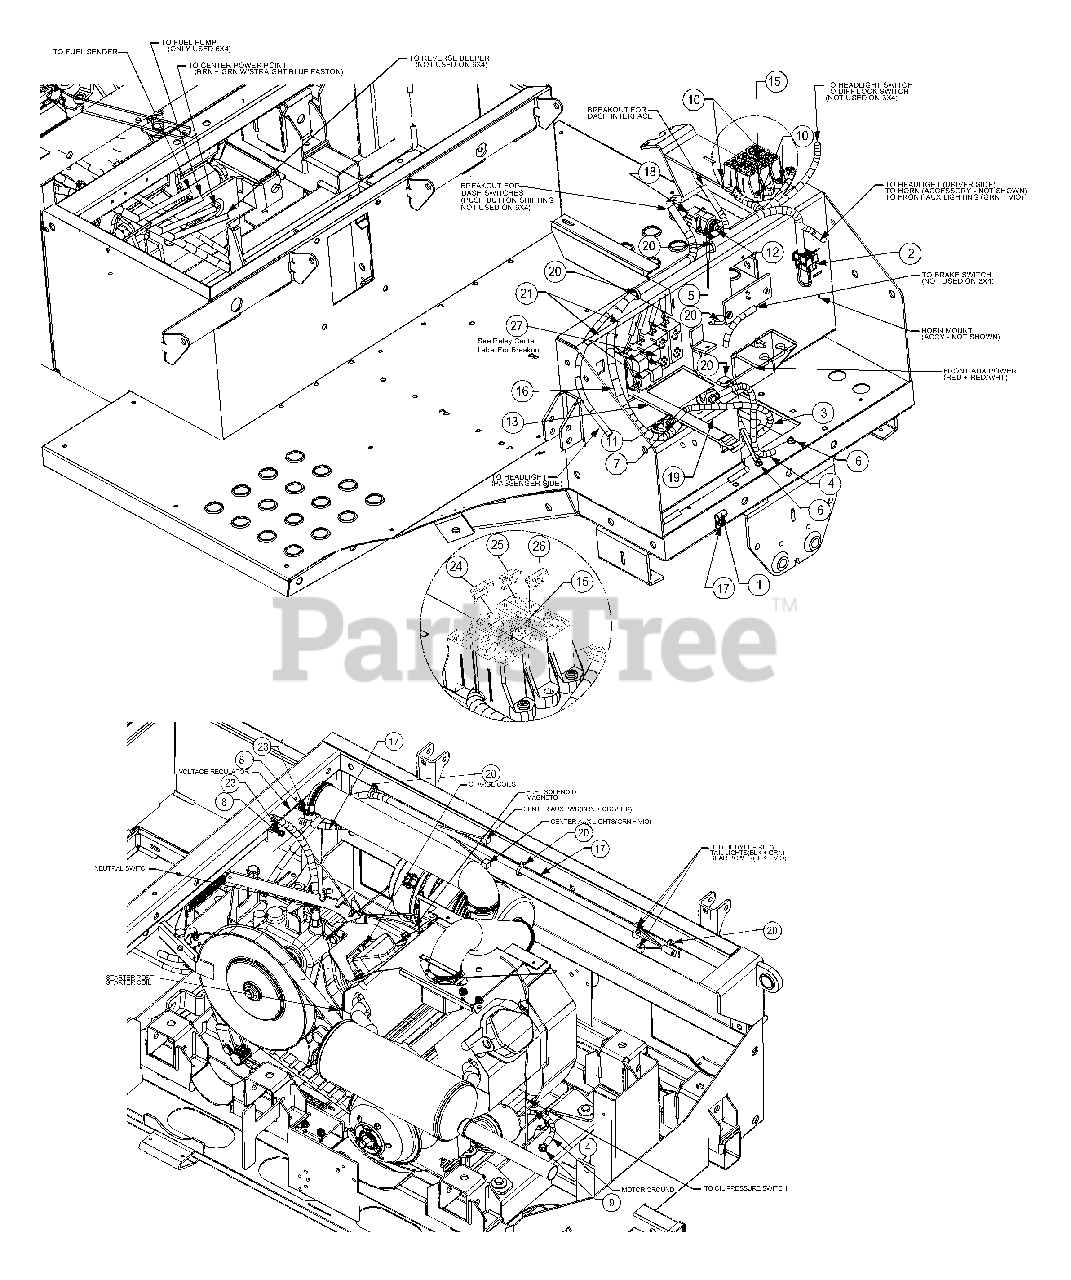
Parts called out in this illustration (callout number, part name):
1	Bracket, Retainer Hook
2	Connection Assembly
3	Harness Assembly, Utility Starter
4	Harness Assembly, Ground
5	Screw, Self-tapping 1/4-20
6	Screw, Self-tapping, 1/4-20 x 0.500
7	Screw, Hex Carriage, 1/4-20 x .75
8	Screw, Self-tapping, 1/4-20 x 1.000
9	Screw, 5/16-18 x.75
10	Screw, #10-24 x 0.75
11	Nut, Hex Sems, 1/4-20
12	Cover, Protection
13	Strap, Battery
15	Fuse, 5 Amp
16	Harness, Utility Wire, Main
17	Harness, Motor Wire
18	Switch, Interlock
19	Battery, 300 CCA
20	Cable Tie, 19" x 8.39"
21	Clip, Retainer, Panel
23	Lock Washer, 1/4
24	Fuse, 7.5 Amp (Horn)
25	Fuse, 15 Amp (Rear Outlet)
26	Fuse, 30 Amp (Electric Bed Lift)
27	Relay, 12V/40A
